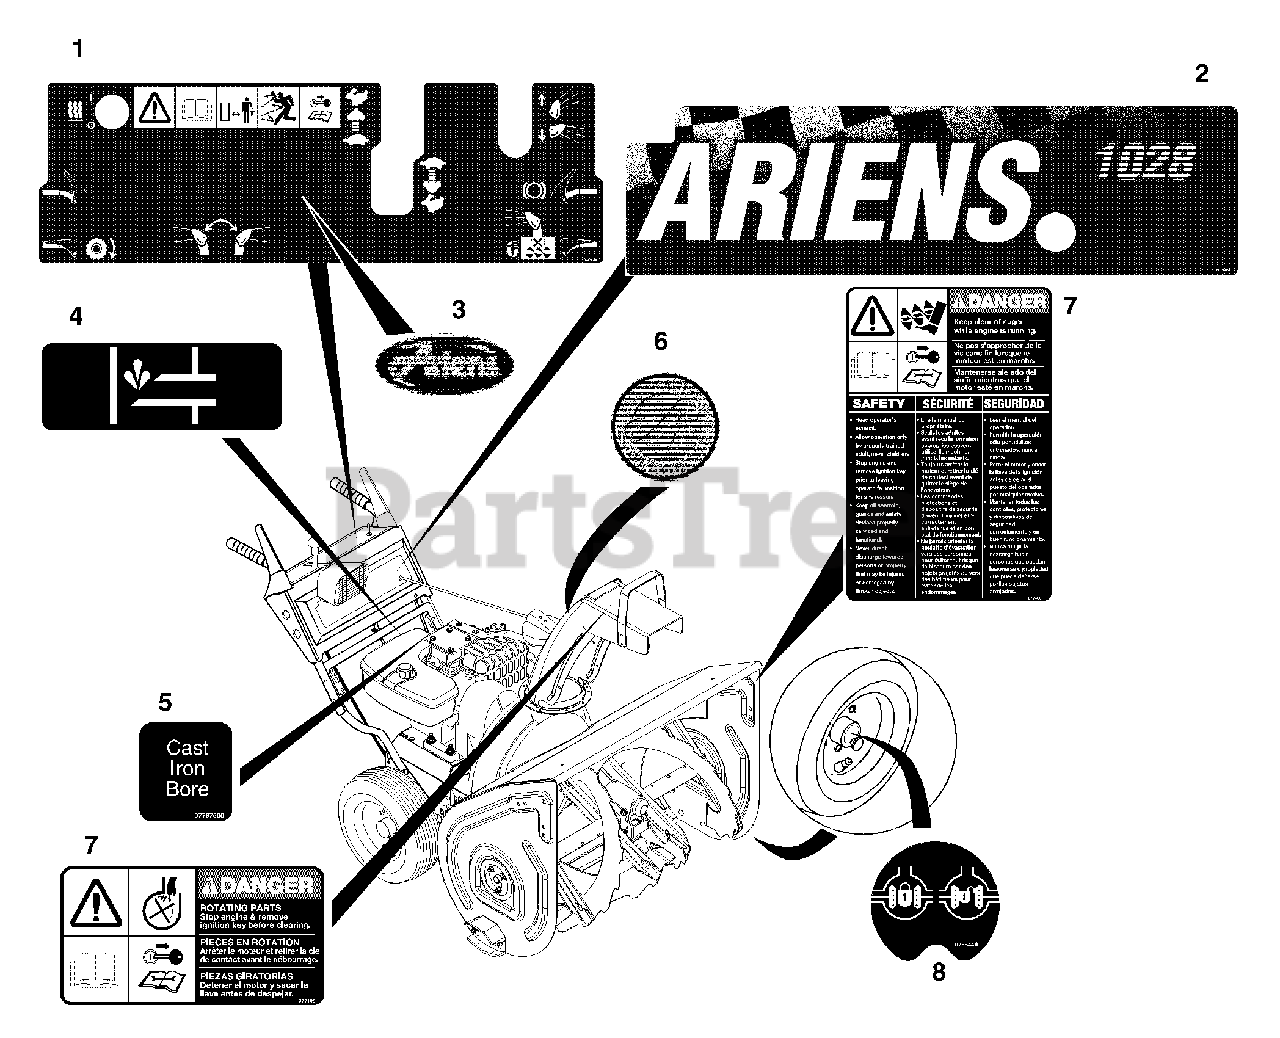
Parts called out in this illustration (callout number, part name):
1	DECAL - 1028 DASH
2	DECAL - 1024 FRONT PANEL
3	DECAL, "ARIENS" JEWEL
4	DECAL, PRIMER "TECUMSEH'S"
5	DECAL - CAST IRON BORE
6	DECAL, A+
7	DECAL SET - DANGER
8	DIFFERENTIAL LOCK DECAL
